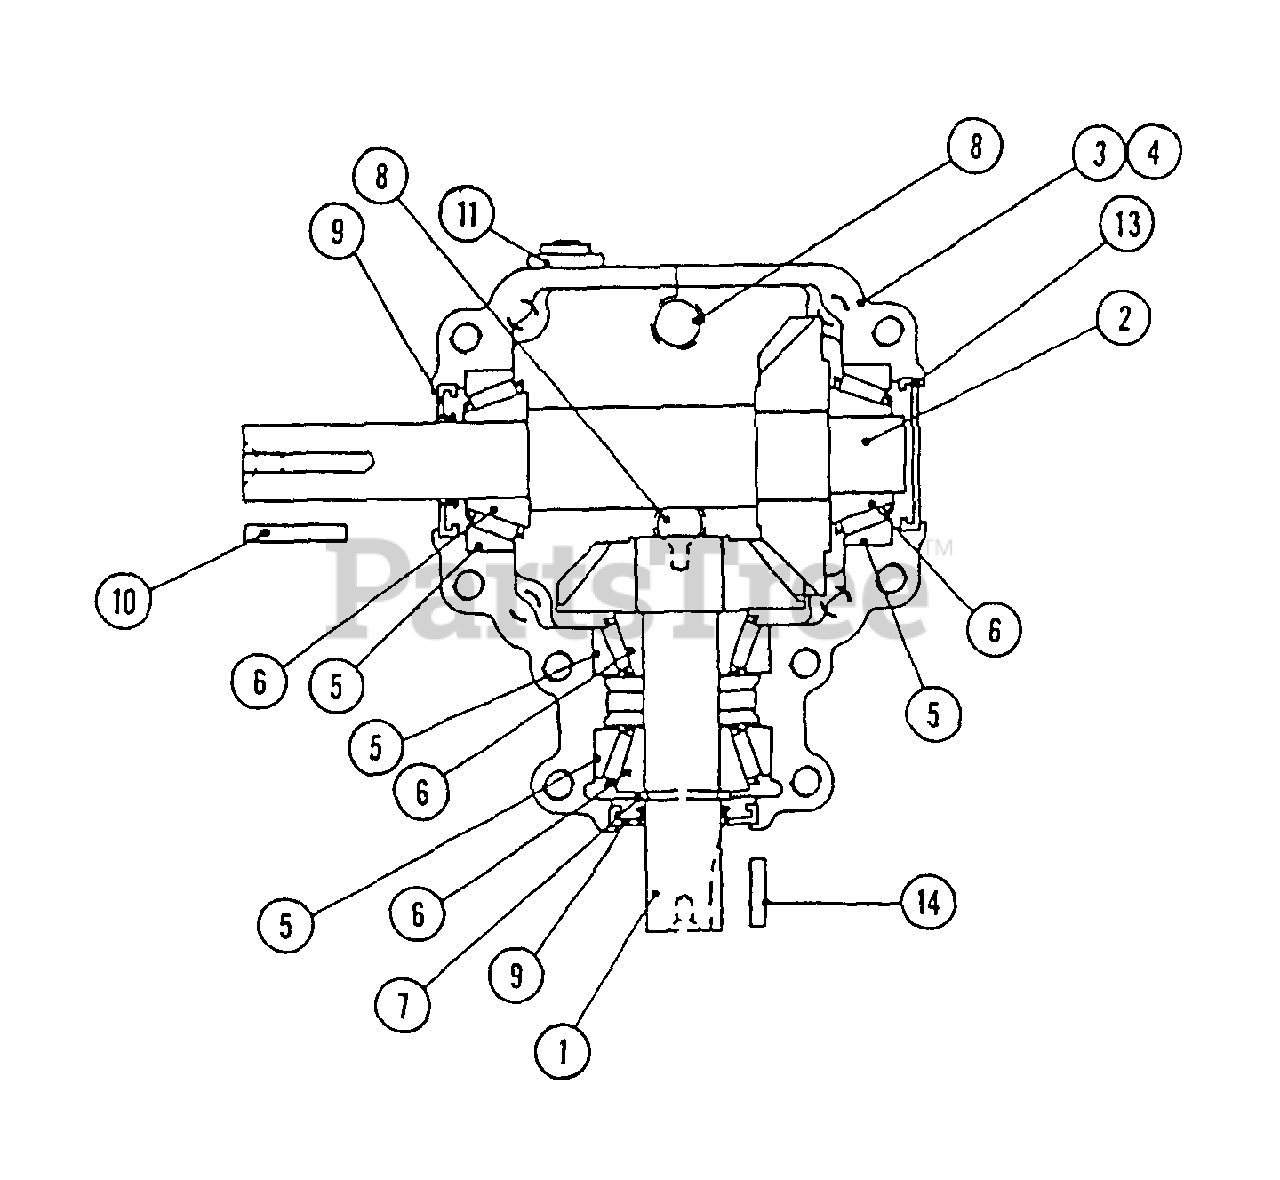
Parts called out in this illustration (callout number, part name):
1	SHAFT - pinion, with gear
2	SHAFT - cross, with gear
3	HOUSING - with tapped holes
5	CUP - bearing
6	CONE - bearing
7	RING - retaining
8	PLUG - pipe 1/4"
10	KEY - 3/16" x 1" input shaft
11	PIPE - vent
13	CAP - end
14	KEY - 3/16" x 5/8" output shaft
